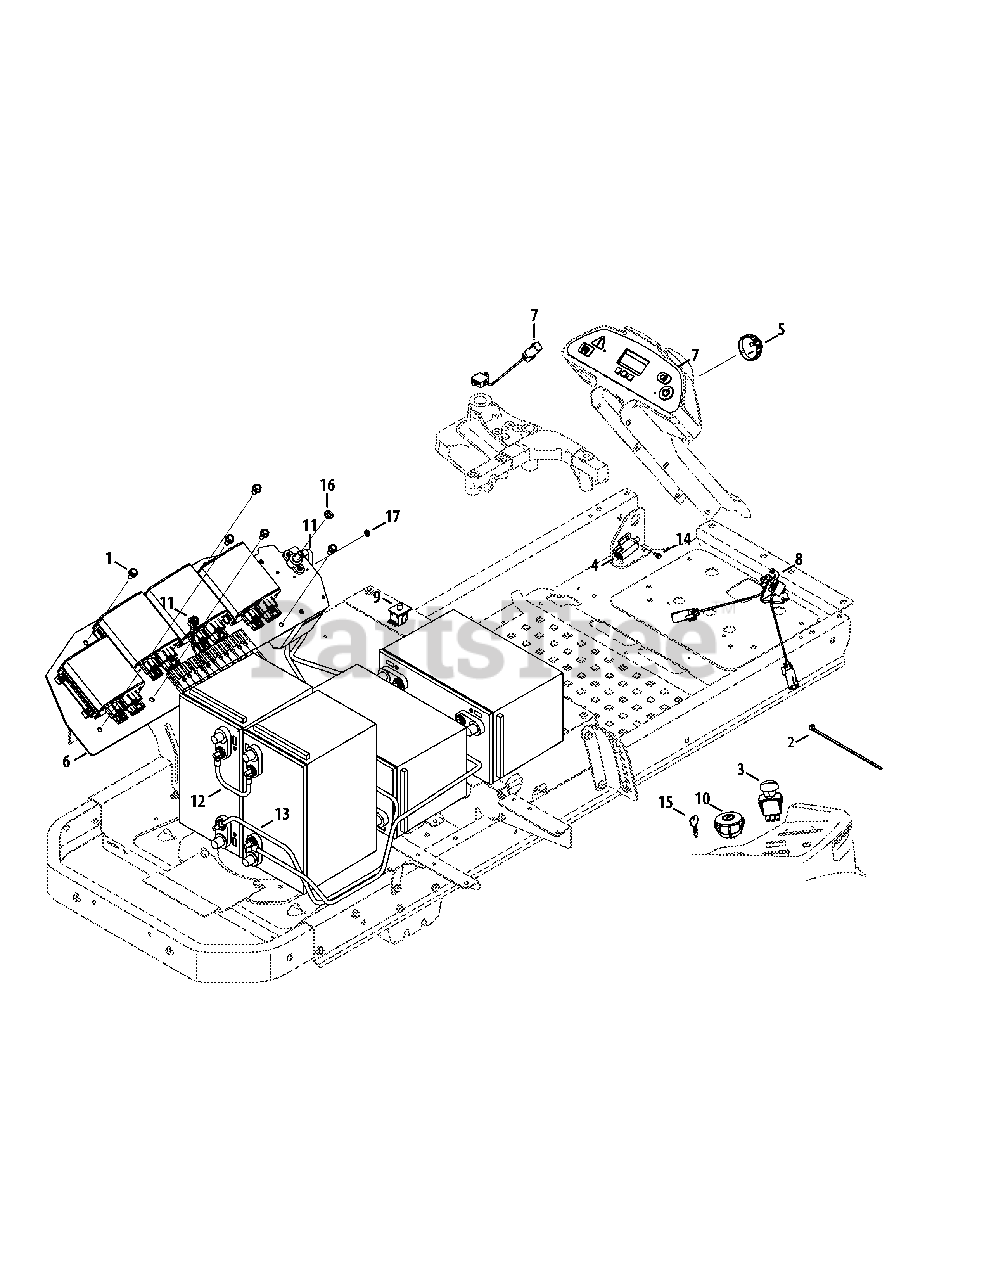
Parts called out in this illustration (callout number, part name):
1	Hex Washer Screw, 5/16-18 x .750
2	Cable Tie
3	Switch, Electric PTO, Yellow Knob
4	Interlock Switch
5	LED Headlight Socket
6	Controller Assembly
7	Control Module Assembly
8	Throttle Sensor
9	Seat Switch
10	Key Switch
11	Electric Battery Harness, 48V
12	Electric Battery Harness, 24V
13	Electric Battery Harness, 12V, 36V
14	Shoulder Screw, #10-32 x .500
15	Key, Assembly
16	Lock Washer, 3/8
17	Lock Washer, 1/4
